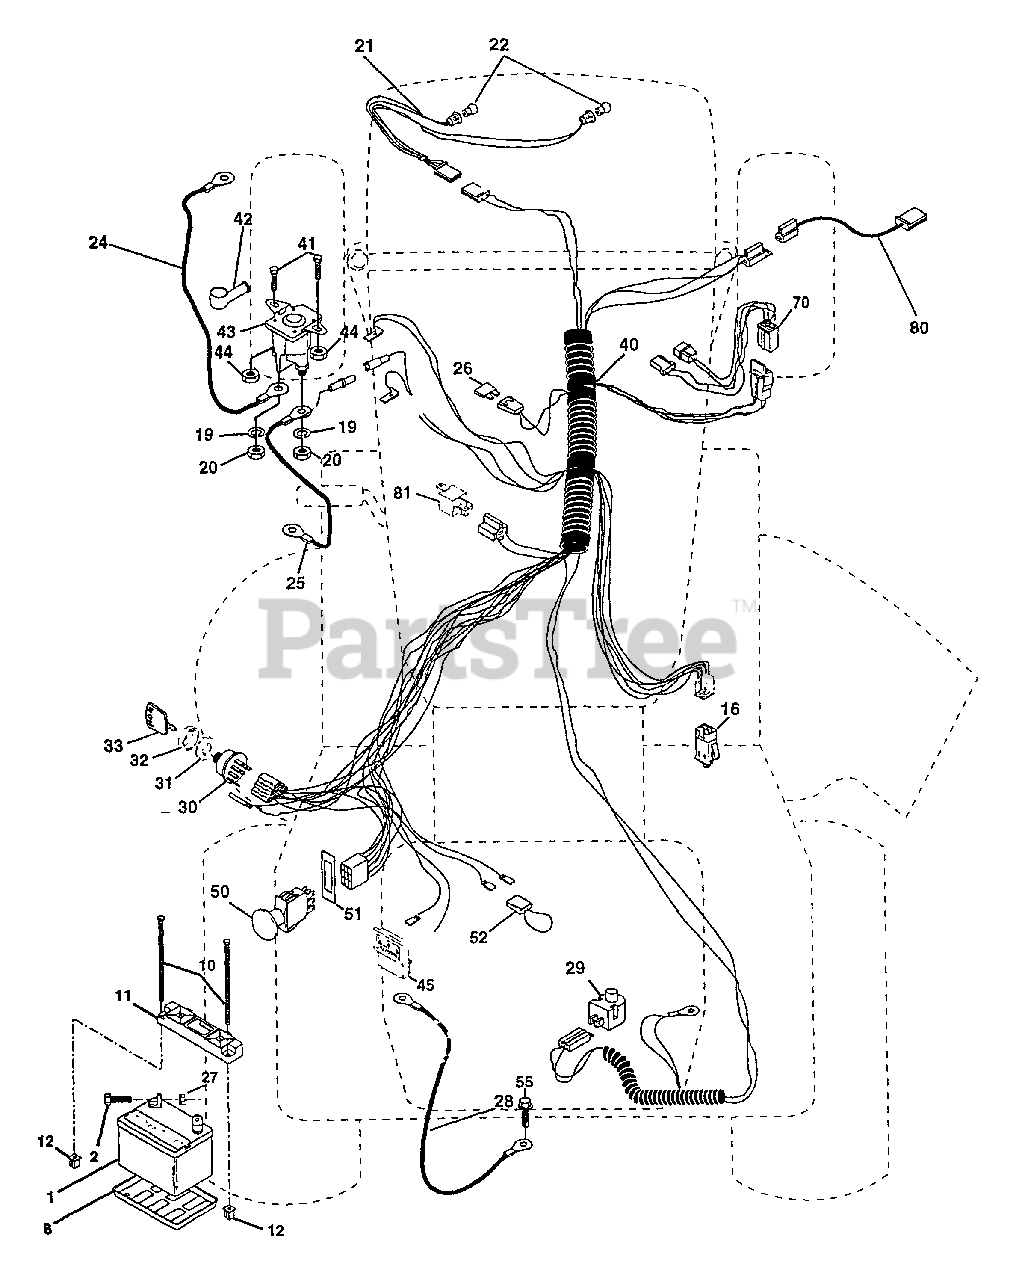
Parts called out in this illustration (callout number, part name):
1	Battery 12 Volt 35 AMP
2	Bolt Hex Hd 1/4-20 UNC X 3/4
8	Tray, Battery
10	Bolt, BTR FRT 1/4-20 x 7.5
11	Hold Down Battery, Front
12	Nut, Push, Nylon
16	Switch Interlock Push-In
19	Washer Lock 1/4
20	Nut Jam Hex 1/4-20 UNC
21	Harness Asm Light W/4152j
22	Bulb Light #1156
24	Cable Battery 6 Ga 11" red
25	Cable Batterywire
26	Fuse 15 AMP
27	Nut Keps Hex 1/4-20 Unc
28	Cable Ground
29	Switch Plunger Normal OP Olive
30	Switch Ign 4 pos w/lights
31	Nut Ignition
32	Cover Sw Ignition
33	Key Ign Molded Indak
40	Harness Ign.
41	Bolt Blk Fin Hex 1/4 - 20 x 1/2
42	Cover Terminal Red
43	Solenoid
44	Nut Keps Hex 1/4-20 UNC
45	Ammeter Rectangular
50	Switch, PTO 3PDT Black Delta 96
51	Ring Retainer PTO
52	Protection Wire Loop
55	Screw Thdrol 5/16-18 x 1/2
70	Harness, Eng.
80	Harness, Clutch EVX
81	Relay Asm
